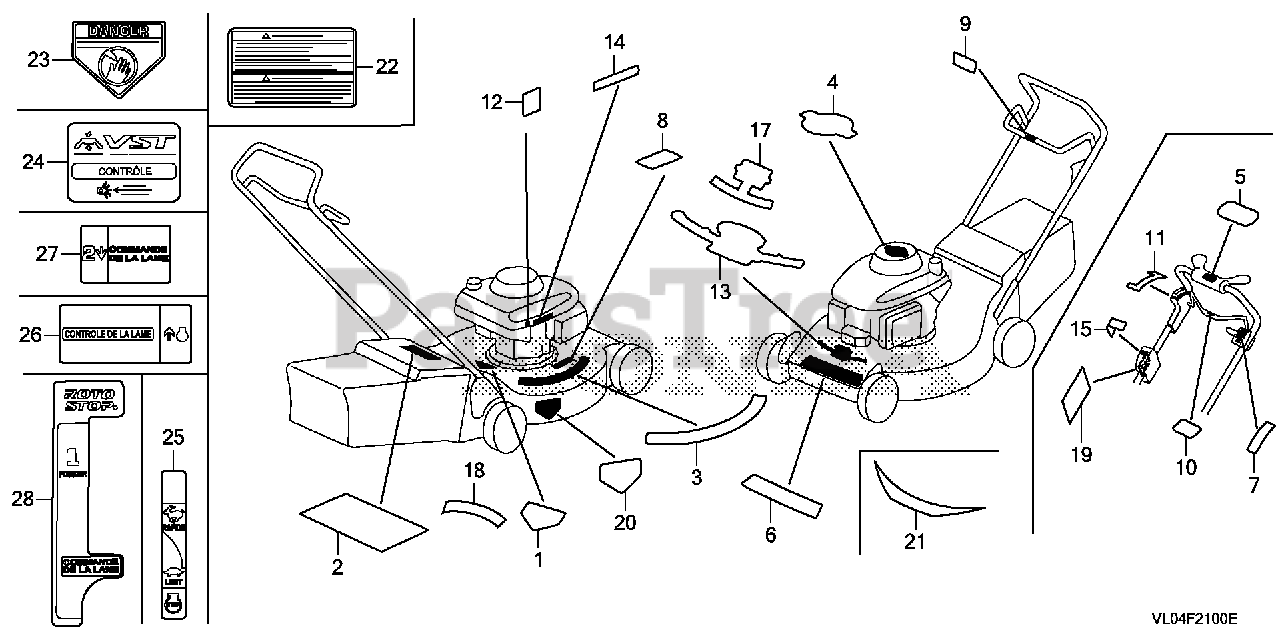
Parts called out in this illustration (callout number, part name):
2	LABEL, WARNING (ENGLISH)
5	MARK, CLUTCH INDICATION (ENGLISH)
7	MARK, THROTTLE INDICATION
8	LABEL, HEAT WARNING
10	MARK, BLADE CONTROL (ENGLISH)
11	MARK, ROTO-STOP CONTROL (ENGLISH)
17	MARK, SALES POINT (TWIN BLADE)
18	MARK, CLIP DIRECTOR
20	LABEL C, HOUSING CAUTION
21	MARK, HONDA
